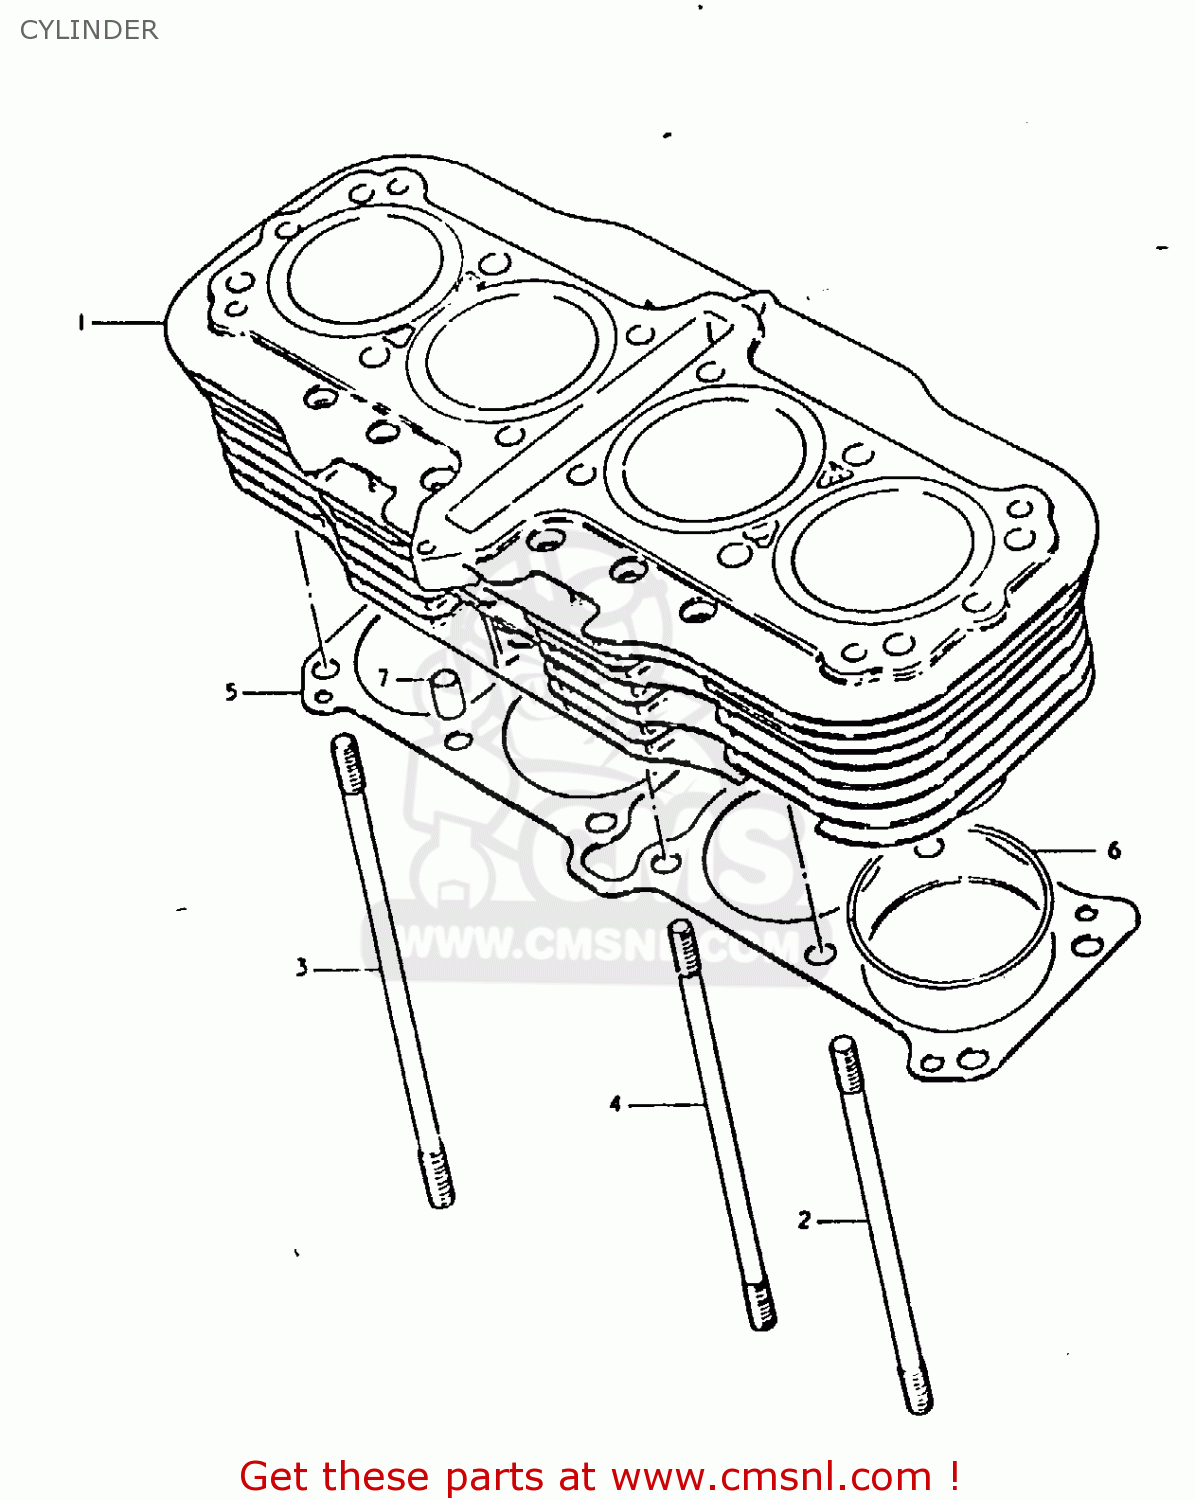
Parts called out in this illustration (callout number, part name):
1	CYLINDER
2	BOLT,STUD
3	STUD
4	BOLT,STUD
5	GASKET,CYLINDER (MCA)
6	O RING(D:2,ID:74)
7	PIN
